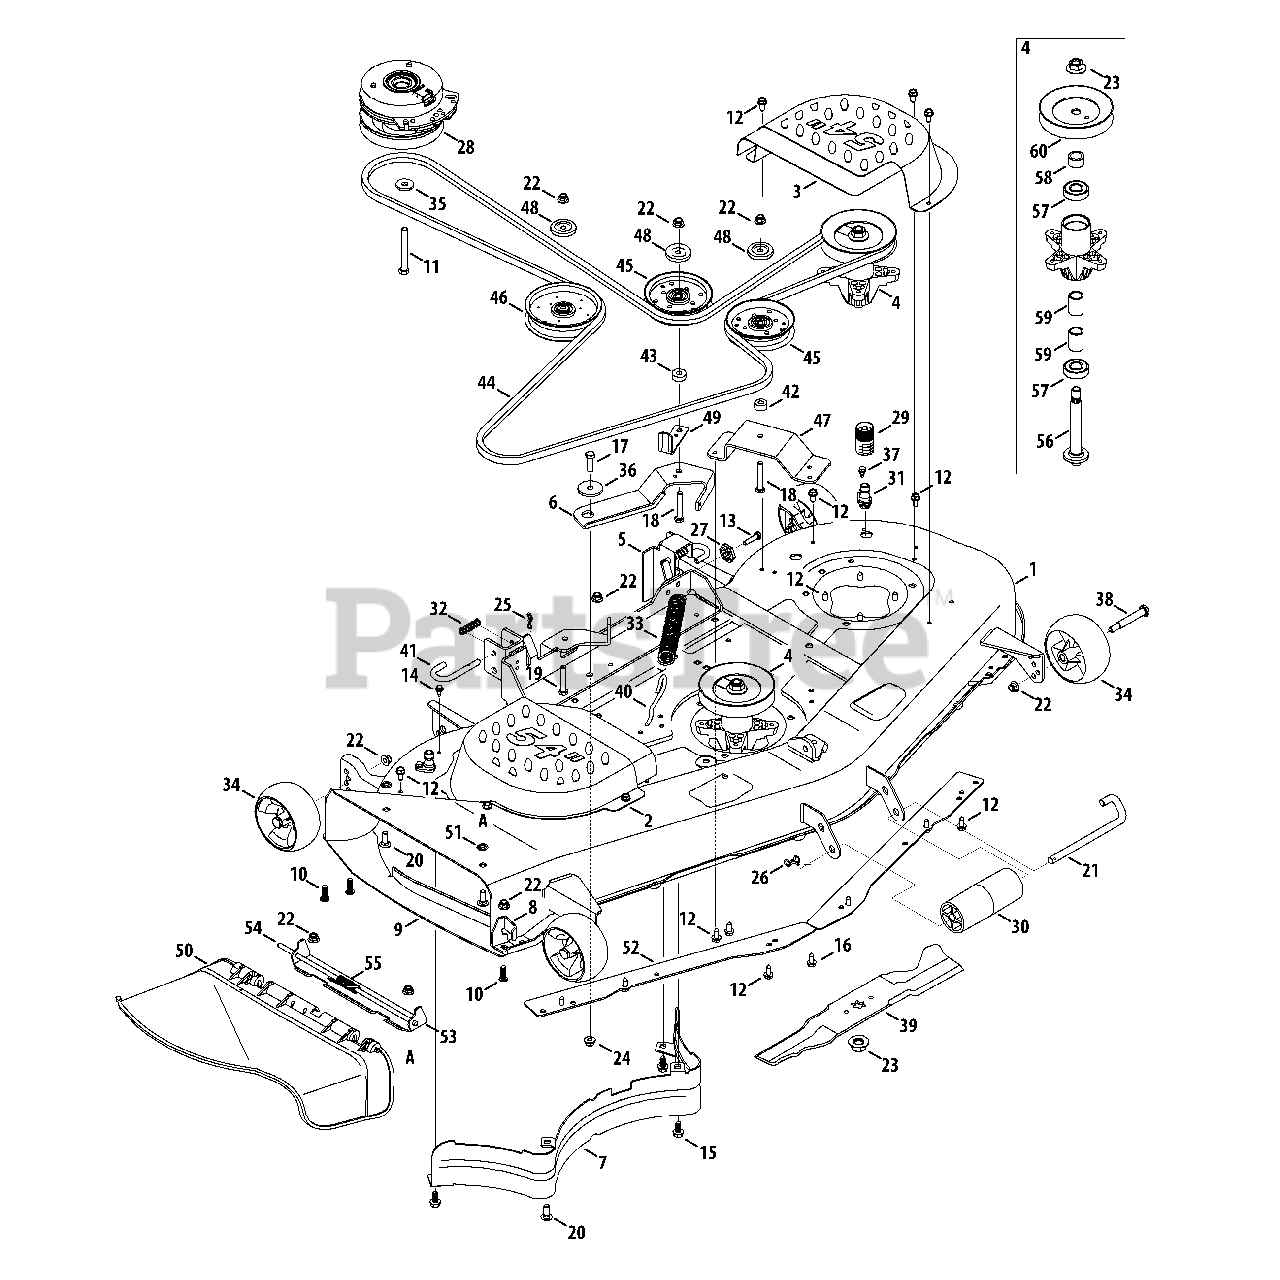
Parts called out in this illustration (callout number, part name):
1	54" Deck Shell
2	Belt Cover, RH
3	Belt Cover, LH
4	Spindle Assembly
5	Deck Lift Bracket
6	Idler Arm
8	Stop Bracket
10	Hex Cap Screw, 3/8-16, 1.00
11	Hex Cap Screw, 7/16-20 x 3.50
12	Hex Washer Screw, 5/16-18 x .750
13	Hex Cap Screw, 5/16-18 x 1.25
14	Hex Washer Screw, 1/4-20 x .500
15	Hex Washer Screw, 3/8-16 x .75
16	Self Tapping Screw, 5/16-18 x .875
17	Hex Cap Screw, 3/8-16 x 1.25
18	Hex Cap Screw, 3/8-16, 2.25
19	Hex Cap Screw, 3/8-16 x 2.00
20	Carriage Screw, 3/8-16 x 1.00
21	Roller Pin, 1/2" x 7.31 Lg
22	Flange Lock Nut, 3/8-16
23	Hex Flange Nut, 5/8-18
24	Flange Lock Nut, 3/8-16
25	Bow-Tie Cotter Pin, 72
26	Bow-Tie Cotter Pin
27	Deck Adjustment Gear
28	Electric PTO Clutch
29	Water Nozzle Adapter
30	Front Roller
31	Deck Wash Nozzle
32	Compression Spring, .535 x 1.751
33	Extension Spring, 1.25 OD x 1.751
34	Deck Ball Wheel, 5.0
35	Flat Washer, .450 x 1.25 x .164
36	Shoulder Spacer, .884 x .190
37	Shoulder Screw, .500 x 1/4-20
38	Shoulder Screw, .5 x 2.5 x 3/8-16
39	Blade, 18.5
40	Deck Spring Rod
41	Deck Hanger Rod
42	Spacer, .385 ID x .875 OD x .458
43	Spacer, .406 ID x 1.00 OD x .380
44	V-Belt
45	Idler Pulley, 4.25 Dia
46	Idler Pulley, 5.00 Dia.
47	Bracket, Idler, Stationary
48	Pulley Cap
49	Belt Guard Bracket
50	Discharge Chute Assembly
51	Push Nut, 3/8
53	Chute Bracket
55	Torsion Spring
56	Spindle Shaft, 6.11 Long
57	Ball Bearing
58	Spacer, .82 x 1.15 x .69
59	Spacer, .792 x 1.06 x 1.52
60	V-Type Pulley, 5.39
